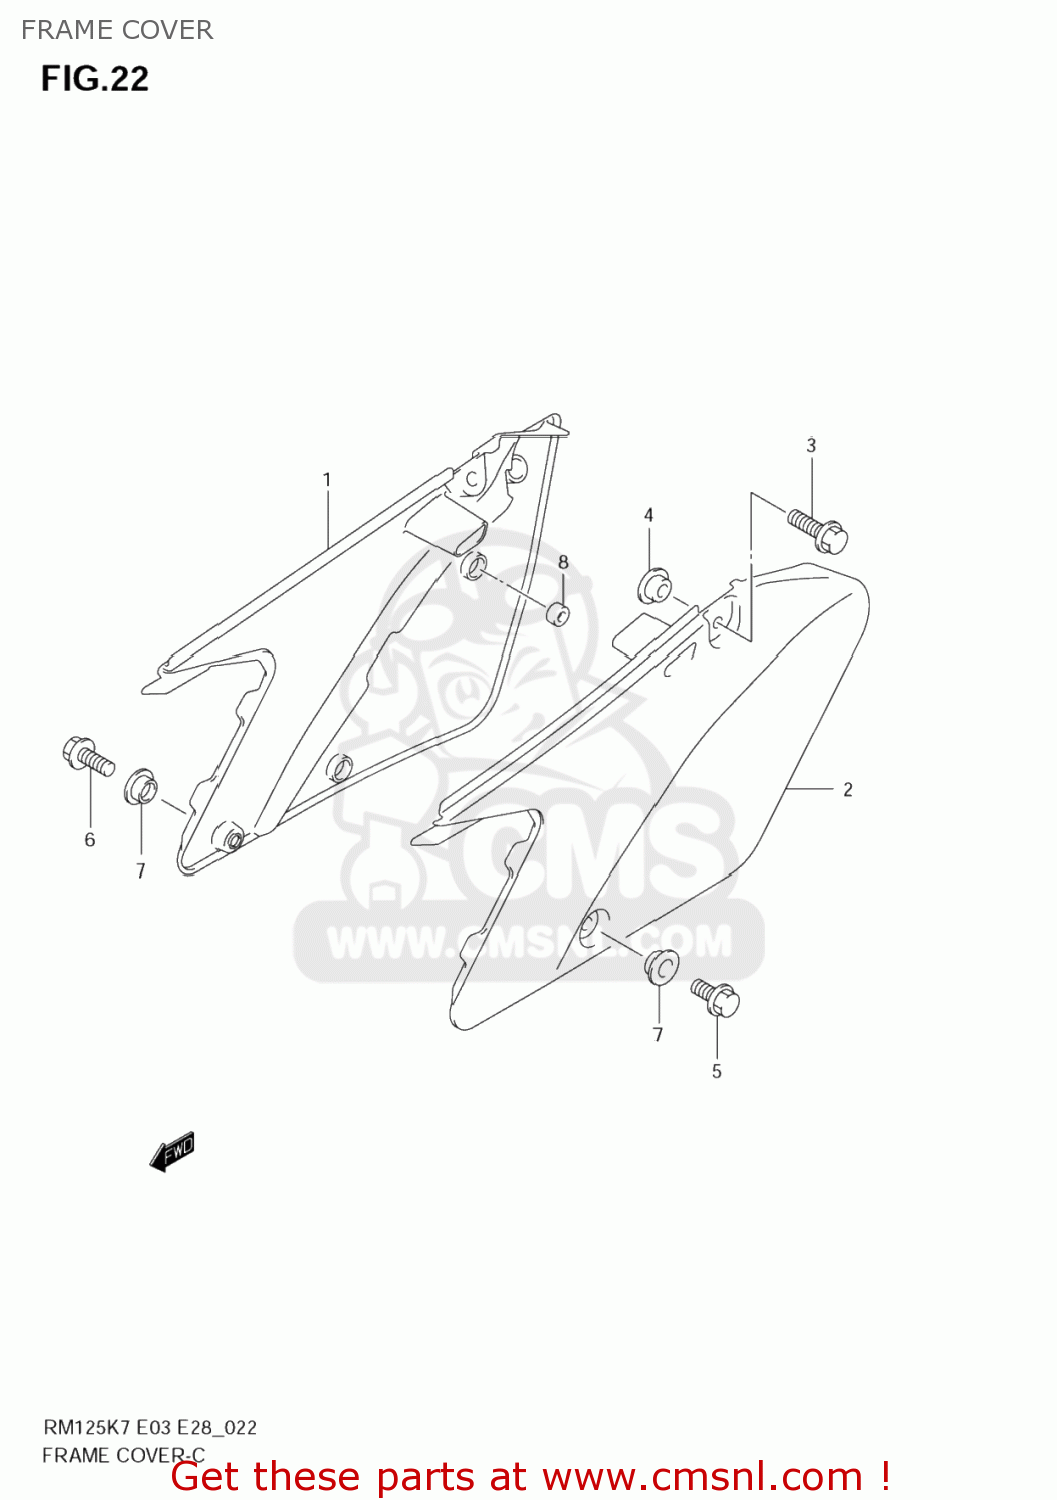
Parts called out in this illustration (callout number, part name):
1	COVER,FRAME,R(WHITE)
2	COVER,FRAME,L(WHITE)
3	BOLT(6X20)
4	WASHER
5	BOLT(6X12)
6	BOLT(6X16)
7	WASHER
8	CUSHION,FRAME COVER,R
